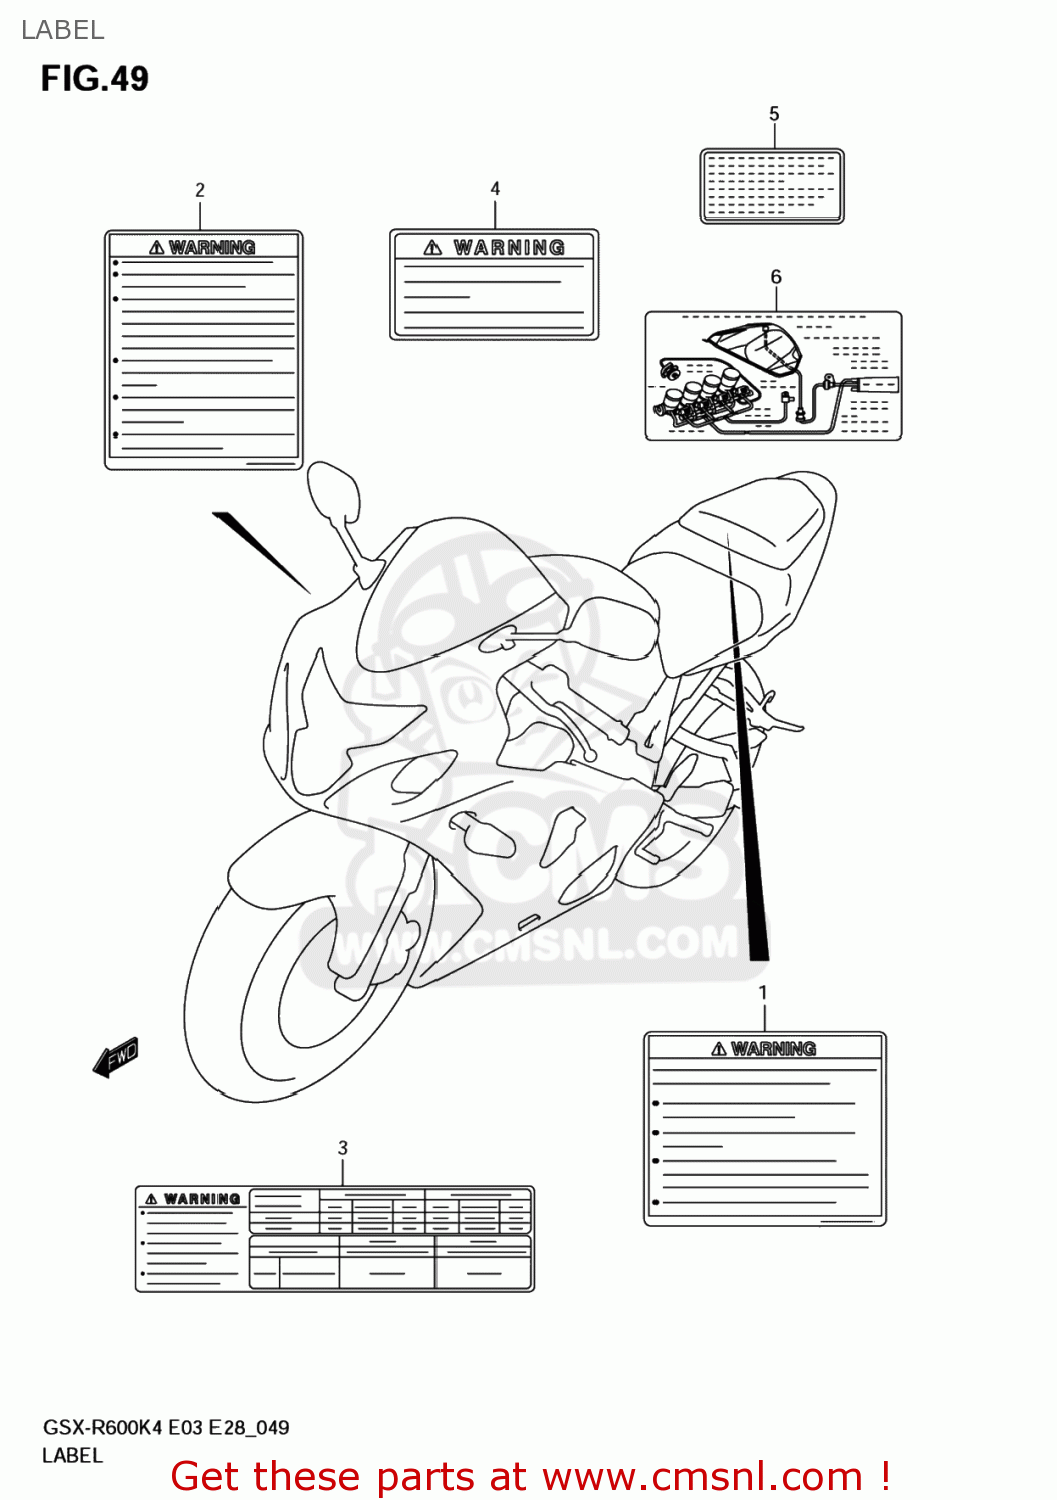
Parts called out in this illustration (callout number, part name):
1	LABEL,GENERAL WARNING
2	LABEL,SCREEN
3	LABEL,TIRE INFORMATION
4	LABEL,WARNING STEERING
5	LABEL,MANUAL NOTICE
6	LABEL,VACUUM HOSE ROUTING
7	MANUAL,OWNER'S
